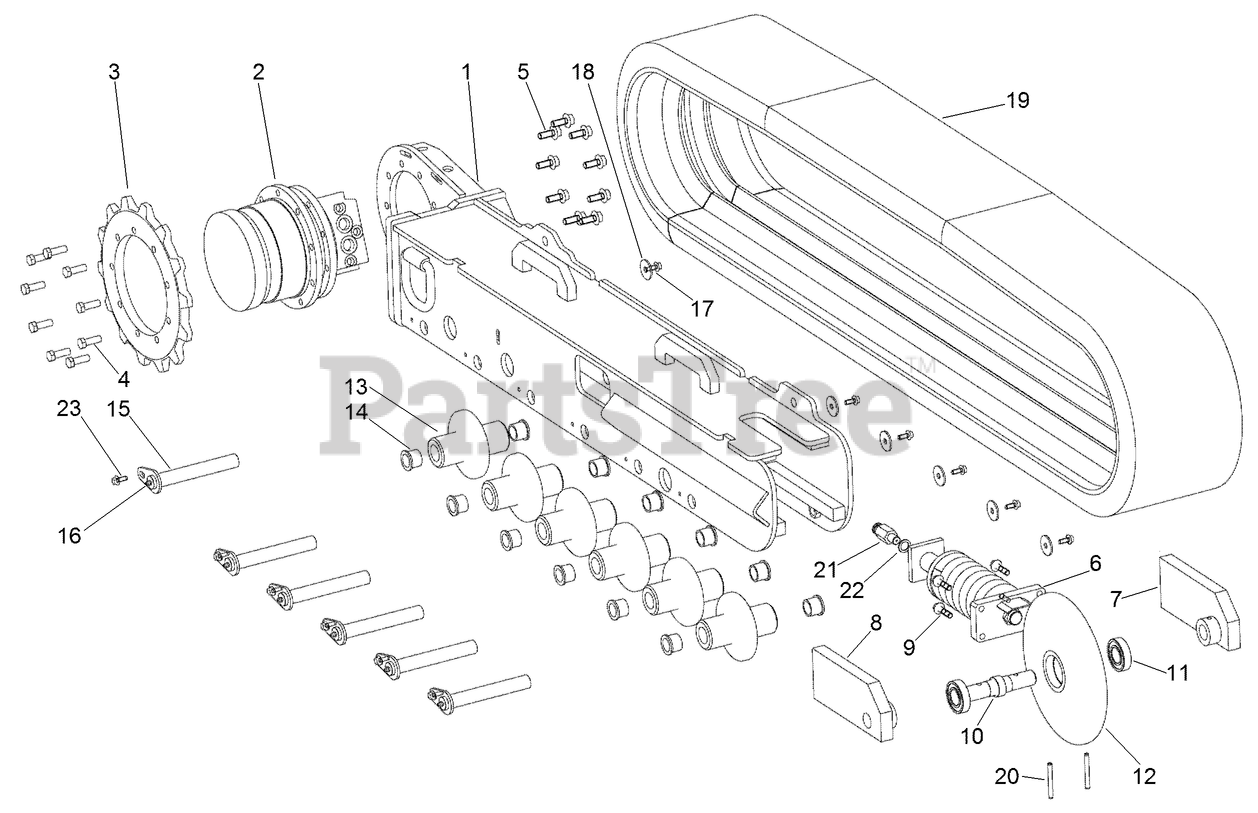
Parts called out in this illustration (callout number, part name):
1	WELDMENT - Track, LH
2	PLANETARY GEARBOX ASM
3	SPROCKET DRIVE
4	BOLT - Thd to Hd M12 x 35 CL8.8 ZND
5	SCREW, METRIC FLANGE w/BODY-M12 x 30
6	TENSIONER-TRACK, SPRING/GREASE
7	BRACKET - Idler, Right
8	BRACKET - Idler, Left
9	SCREW-FLANGE
10	PIN-MOUNT, IDLER
11	BEARING-BALL
12	WHEEL - Idler Track
13	ROLLER - Track
14	BEARING-PLAIN, FLANGED
15	PIN-FLAG
16	FITTING-Lube 1/4-28 Tpr SAE-LT .54 Long
17	SCREW, METRIC FLANGE w/BODY - M8 x 20
18	WASHER - .406 x 1.50 x .119 in CST ZND
19	TRACK-RUBBER
20	PIN-SPRING
21	VALVE-GREASE
22	SEAL-O RING
23	SCREW-FLANGE
